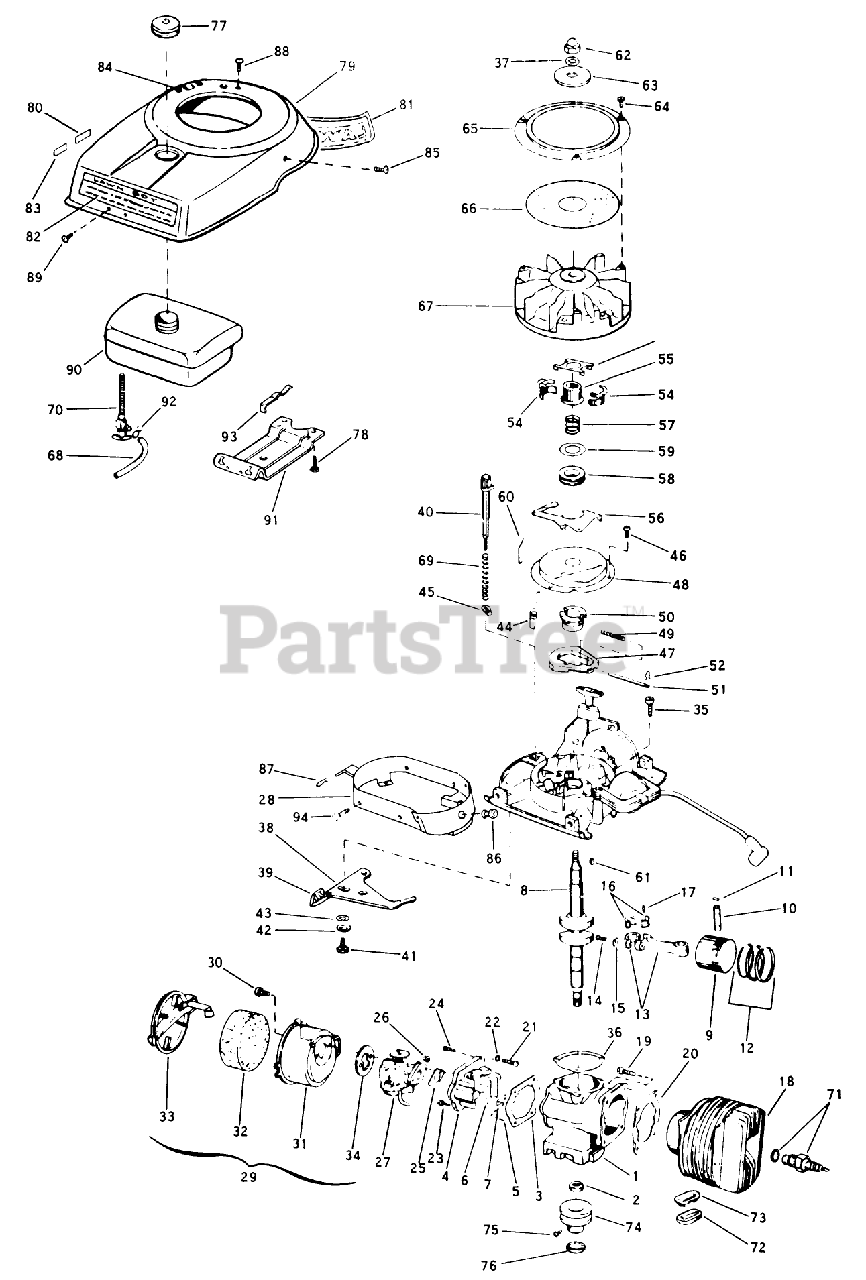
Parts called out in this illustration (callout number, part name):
7	PLATE-BACKUP, REED
11	RING-RETAINING
16	LINER ASM
20	GASKET S
23	SCREW S
24	SCREW S
25	GASKET S
26	STOP NUT
30	SCREW S
32	AIR FIL.ELEM S
36	GASKET S
46	SCREW S
47	FLYWEIGHT S
48	DUST COVER S
49	SPARK ADV. SPRING S
50	SPARK ADV. S
51	PIN,SPARK ADV. S
52	SPARK ADJ. SPRING
55	COLLAR S
56	LEVER-GOVERNOR S
57	SPRING S
58	THRUST COLLAR S
65	Ring-Flywhl. Scrn.
68	GAS LINE
69	SPRING S
70	VALVE&SCREEN SM
71	Spark Plug
72	GASKET S
78	SCREW S
85	SCREW S
86	NUT-CLIP
92	CLAMP - HOSE S
94	SCREW S
